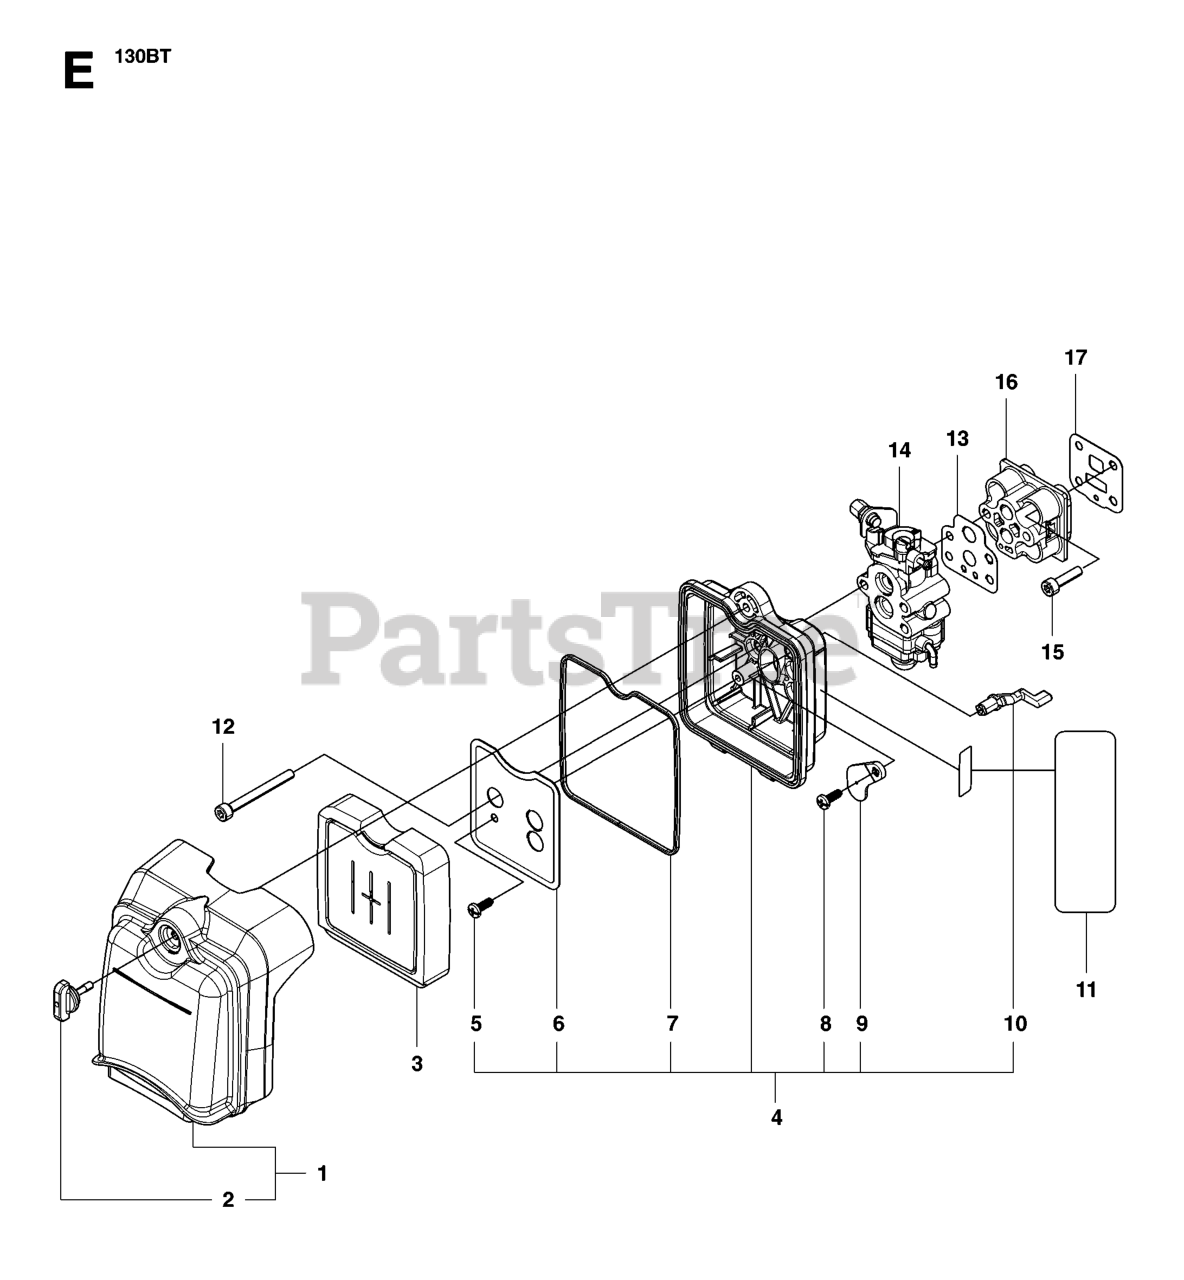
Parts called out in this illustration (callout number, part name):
4	BODY AND SCREEN
11	LABEL, CHOKE
14	CARBURETOR A
15	BOLT
17	GASKET INSULATOR
